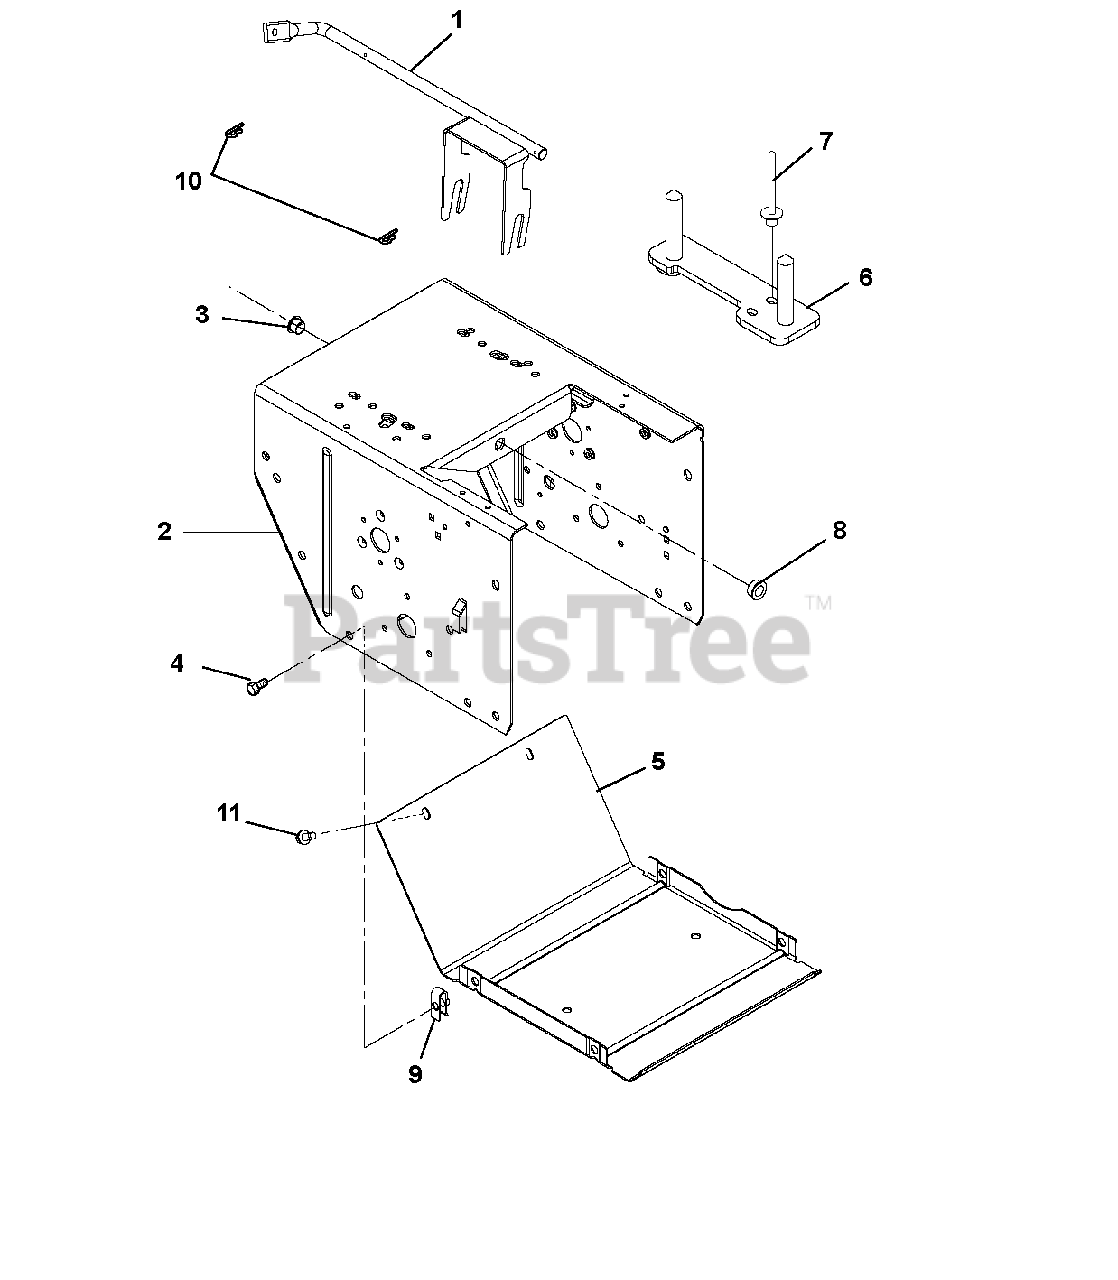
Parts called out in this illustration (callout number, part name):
1	Arm, Shift
2	Main Frame
3	Bushing, Polyliner
4	Bolt, Hex Washer Head .25-20 x .75
5	Cover, Bottom
6	Strap, Engine Bolt
7	Rivet, Pop .187
8	Bushing, Polyliner
9	Nut, Retainer .25-20 x .56
10	Clip, Spring
11	Screw, Tapping Hex Washer Head Thread Rolling .25-20 x .50
